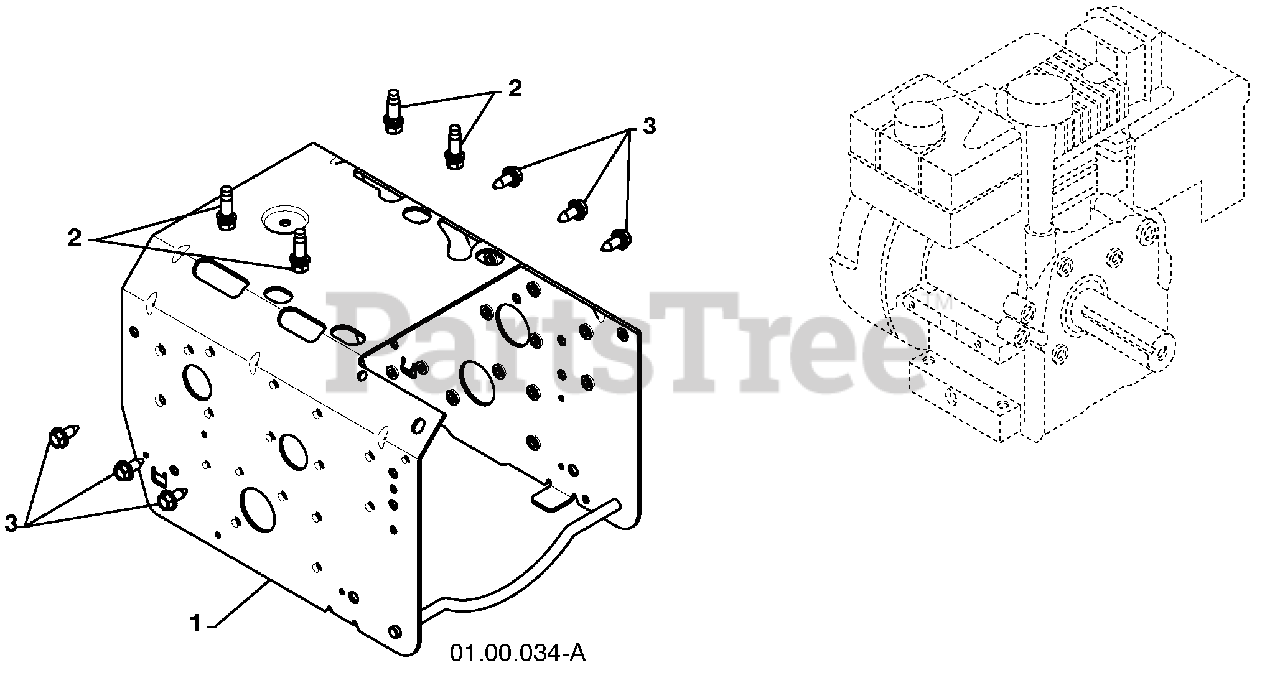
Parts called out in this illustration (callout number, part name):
1	FRAME
2	BOLT 3/8-16
3	SCREW 5/16-18 X .750
